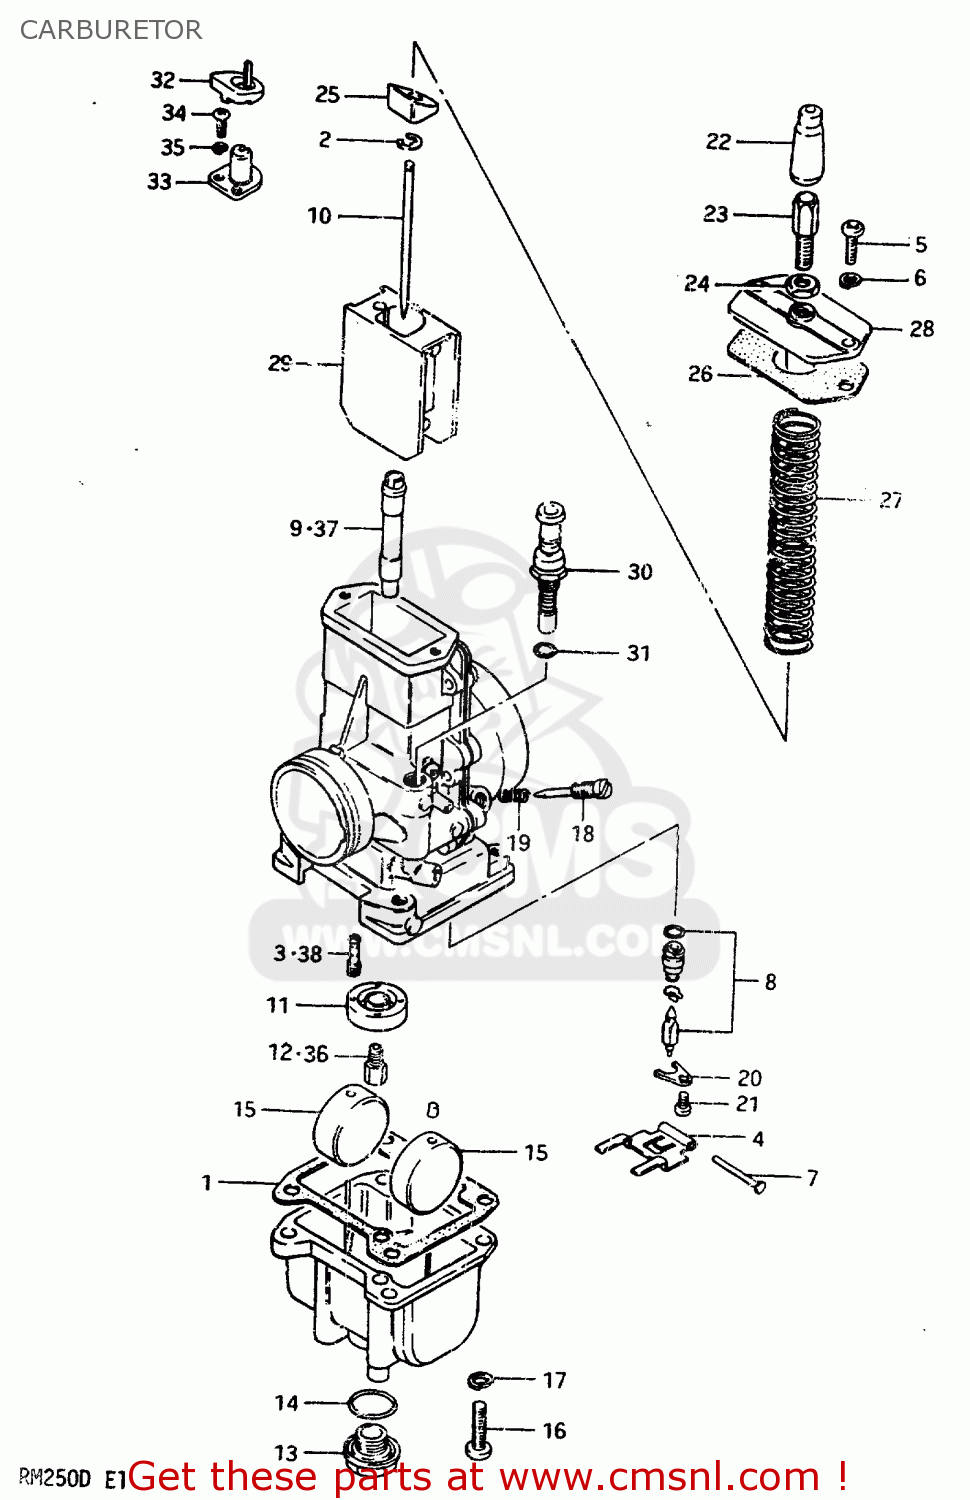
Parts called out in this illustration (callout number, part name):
1	CARBURETOR ASSEMBLY
2	CLIP
3	JET,PILOT
4	ARM,FLOAT
5	SCREW
6	WASHER,LOCK 4M
7	PIN,FLOAT
8	VALVE ASSEMBLY,NEEDLE
9	JET,NEEDLE
10	NEEDLE,JET
11	RING,MAIN JET FIXING
12	JET,MAIN(290)
13	SCREW,GUIDE
14	O RING,DRAIN PLUG
15	FLOAT
16	SCREW 5X20
17	LOCK WASHER
18	SCREW,PILOT AIR
19	SPRING
20	PLATE
21	SCREW 4X6
22	CAP,CABLE ADJUSTER
23	ADJUSTER,CABLE
24	NUT
25	SEAT,RETURN SPRING
26	GASKET,MIXING CHAMBER (NAS)
27	SPRING,THROTTLE VALVE
28	CAP,CARBURETOR,TOP
29	VALVE,THROTTLE
30	PLUNGER ASSEMBLY
31	O-RING
32	SEAT,RETURN SPRING
33	PLATE,NEEDLE JET
34	SCREW
35	WASHER,LOCK
36	JET
37	JET,NEEDLE
38	JET,PILOT
